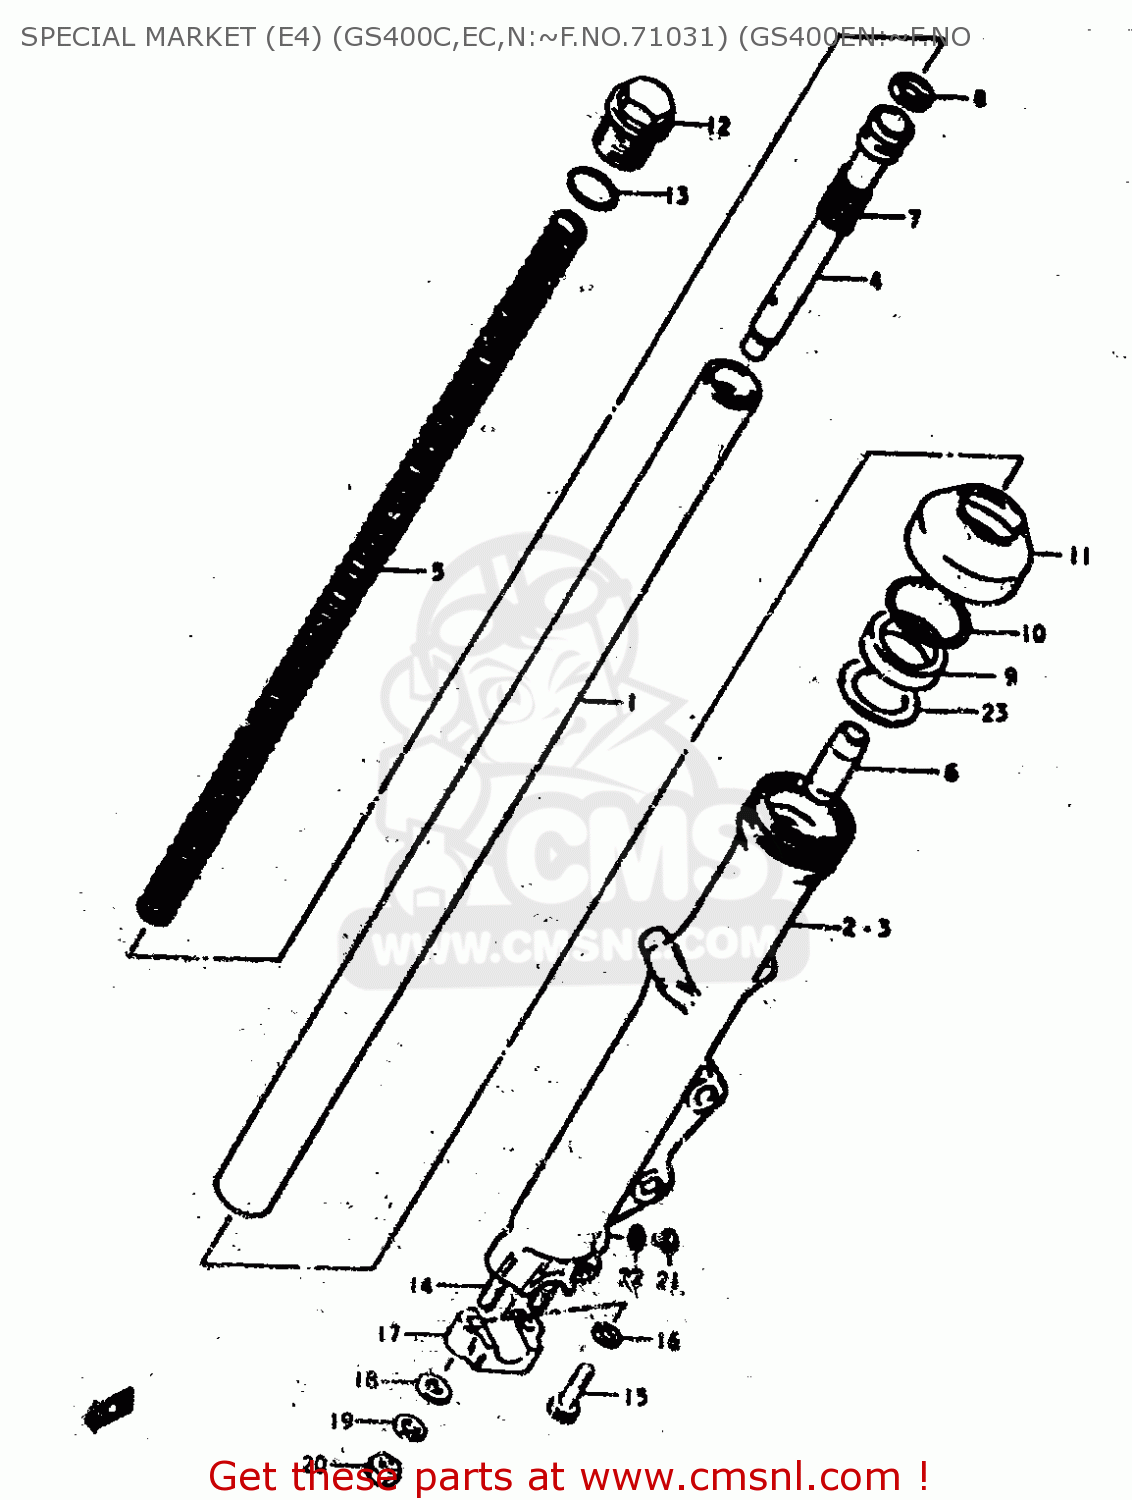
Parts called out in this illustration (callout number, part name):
1	TUBE,INNER
2	TUBE,OUTER,LEFT
3	TUBE,OUTER,RIGHT
4	CYLINDER,FRONT FORK
5	SPRING
6	PIECE,OIL LOCK
7	SPRING,REBOUND
8	RING,PISTON
9	OIL SEAL,FRONT FORK
10	CIRCLIP,FORK OIL SEAL
11	BOOT
12	BOLT
13	O RING
14	STUD 8X25
15	BOLT
16	GASKET (NAS)
17	HOLDER,AXLE
18	WASHER
19	LOCK WASHER
20	NUT
21	SCREW
22	GASKET (NAS)
